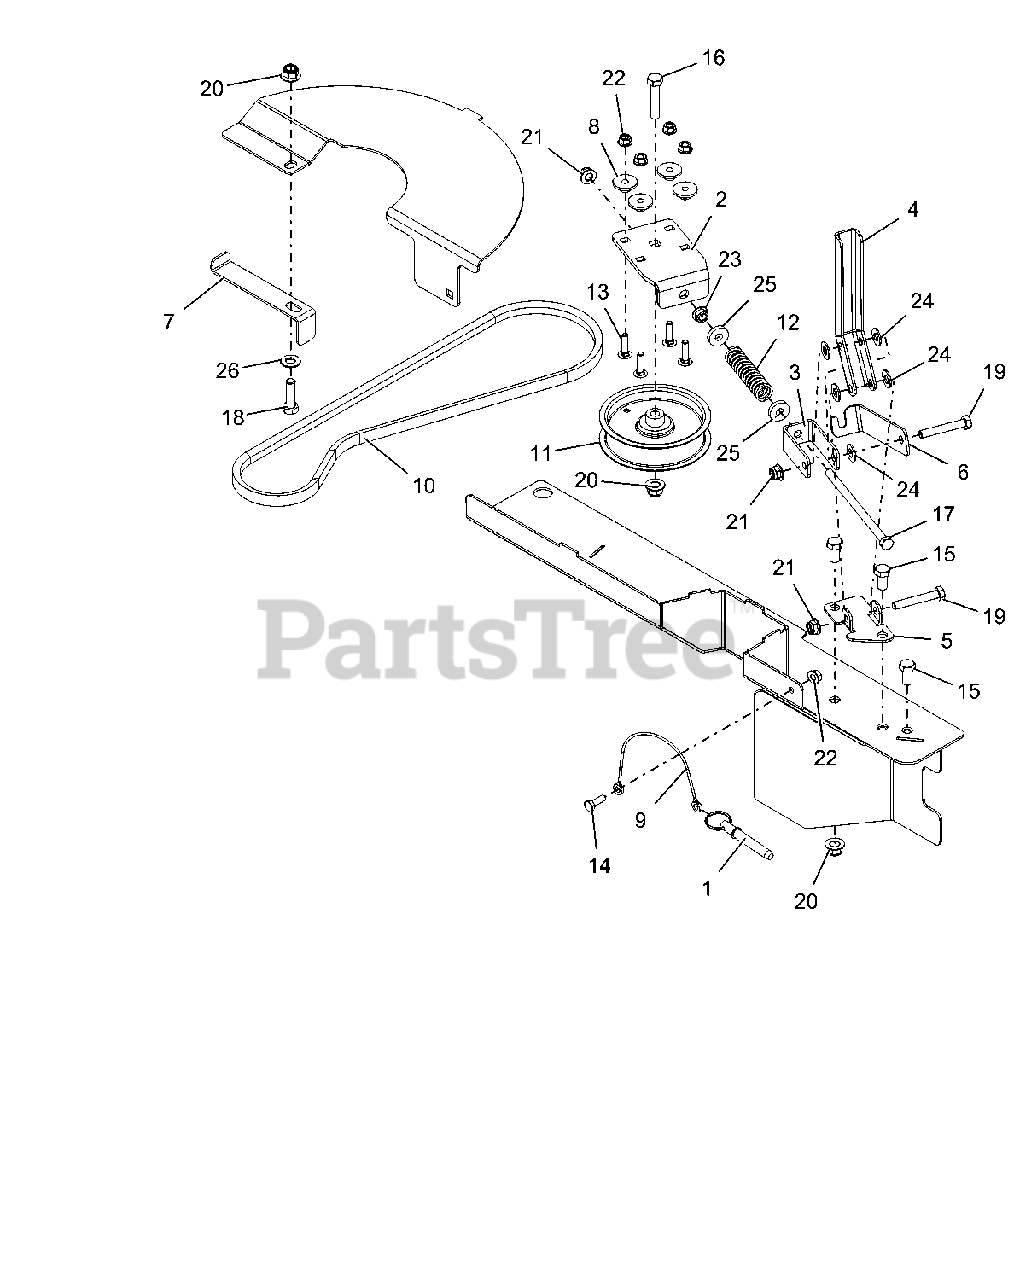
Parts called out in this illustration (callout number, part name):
1	PIN, SPRING BALL .375 OD X 1.50
2	BRKT, ADJUSTABLE IDLER
3	LINK, IDLER RELEASE-BLACK
4	LEVER, IDLER RELEASE-BLACK
5	MOUNT, IDLER RELEASE LEVER-BLK
6	LOCK, IDLER RELEASE LEVER-BLACK
7	FINGER, BELT-BLACK
8	BSHG, FLG .265 X .477 X .375 X 1.00
9	LANYARD, 12"
10	V-BELT, 4L WRAPPED CLUTCHING
11	PULLEY, IDLER 4.00 X .375
12	SPRG, COMPRESSION
13	BLT-RDHDSQNK .25-20X1.00 G5 YWZC
14	BLT-HEX .25-20X.75 GR5 YWZC
15	BLT-HEX .38-16X.75 GR5 YWZC
16	BLT-HEX .38-16X1.75 GR5 YWZC
17	BLT-HEX .31-18X5.50 GR5 YWZC
18	BLT-HEX .38-16X1.25 GR5 YWZC
19	BLT-HEX .31-18X2.00 GR5 YWZC
20	NUT-LK-NYL-FLG .38-16 YWZC
21	NUT-LK-NYL-FLG .31-18 YWZC
22	NUT, LK-TOP-FLG .25-20 YWZC
23	@NUT-SPNLK-FLG .312-18 YWZC
24	WSHR-FL-NYL .375X.75X.060
25	WSHR-FL-STL .328X.87X.179 YWZC
26	WSHR-FL-STL.406X.812X.065 YWZ
